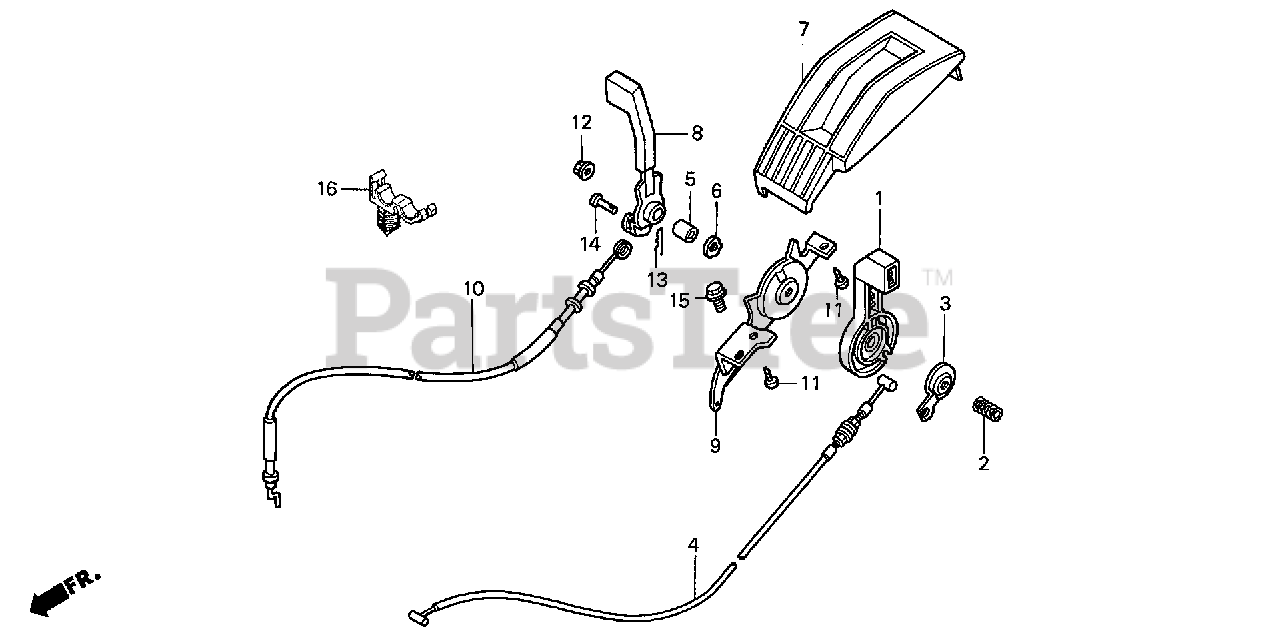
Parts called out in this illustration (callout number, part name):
1	LEVER, THROTTLE
2	SPRING, THROTTLE LEVER
3	SEAT, SPRING
4	CABLE, THROTTLE
5	COLLAR, RECOIL STARTER
6	WASHER, WAVE (11MM)
7	COVER, CONTROL
8	LEVER, CHANGE
9	PLATE, STOPPER
10	CABLE, CHANGE
11	SCREW, TAPPING (5X12)
12	NUT, FLANGE (6MM)
13	PIN, LOCK (6MM)
14	PIN A, BRAKE ROD JOINT
15	BOLT, FLANGE (6X10)
16	GUIDE, CABLE (USED TO PREVENT CHANGE CABLE FROM CONTACTING FUEL TANK)
